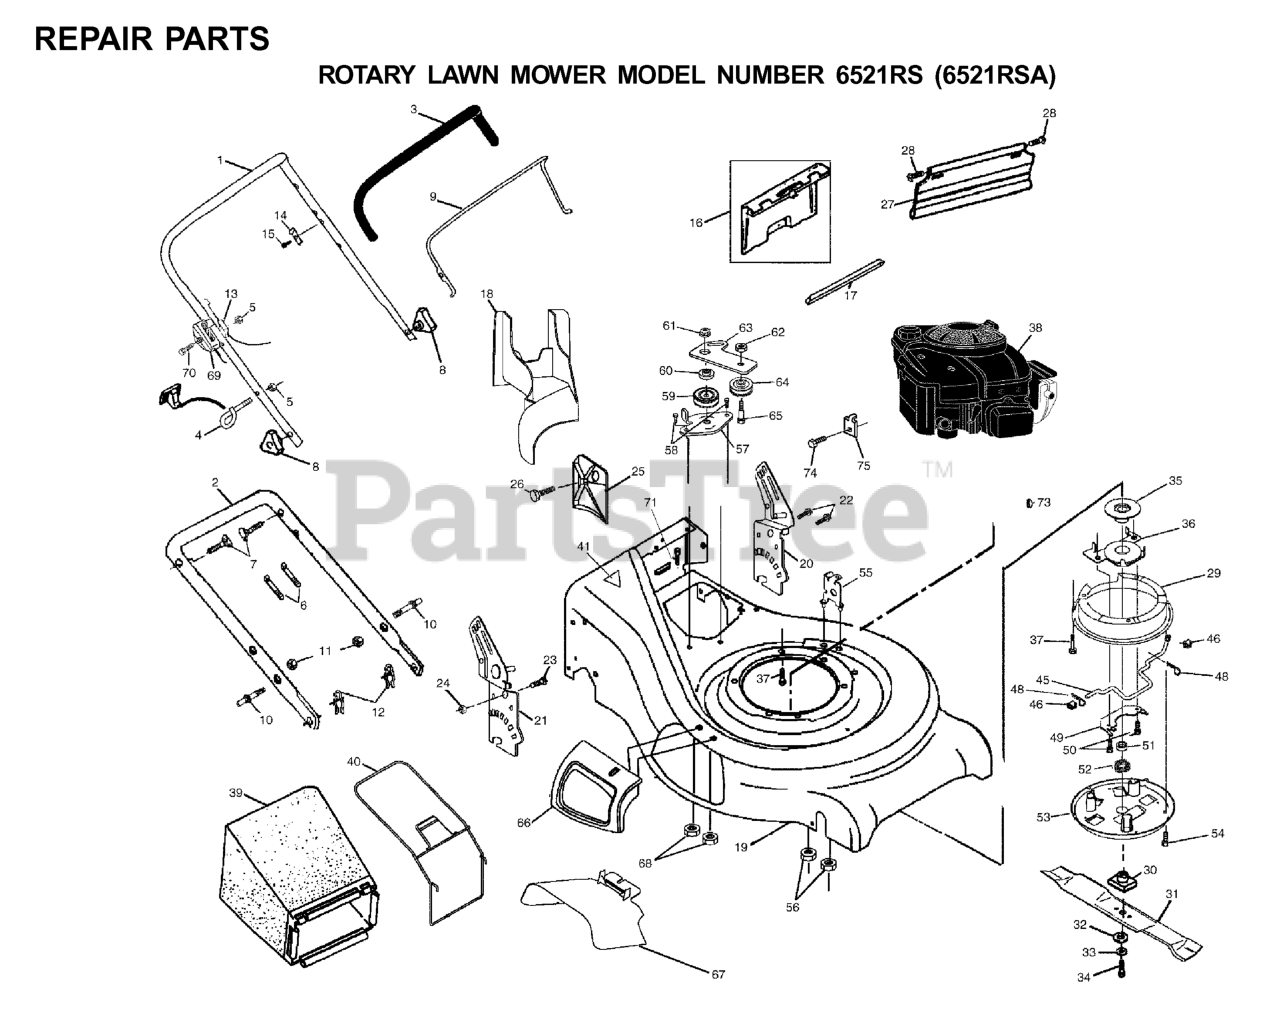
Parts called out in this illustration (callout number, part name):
1	HANDLE UPPER DLX COMF
2	HANDLE
3	GRIP.HANDLE.FOAM
4	ROPE GUIDE
5	NUT
6	TIE GUIDE
7	HANDLE BOLT
10	BOLT
11	NUT
12	HAIRPIN COTTER
13	ENGINE ZONE CONTROL
14	BRACKET UPSTOP
15	SCREW.HEX.HEAD.WASHER.10-16
16	KIT.DOOR.REAR.21.WRAPPED.BLACK
17	SEALING
18	MULCH PLUG
20	.RACKET
21	RIGHT HANDLE BRKT. ASSM.
22	SELF-TAPPING SCREW 5/16-18X3/4
23	BOLT, HEX HEAD 5/16-18
24	LOCKNUT
25	CLIPPING DEFLECTOR
27	REAR SKIRT
28	HINGE SCREW
29	BELT COVER, TOP
30	BLADE ADAPTOR
31	21" MULCH BLADE PREMIUM
32	WASHER,HARDEN
33	LOCKWASHER
34	SCREW, HEX HD 3/8-24 X 1-3/8
35	PULLEY, FIXED
36	BEARING SUPPORT ASM
37	BOLT 3/8-16X1-1/8
39	Grass Catcher Bag
40	FRAME.GRASS.CATCHER.WALK.21"
41	DECAL HYT
45	ROD.PULLEY.ENGAGE
46	BUSHING.PIVOT.ROD
48	RETAINER CLIP
49	CLAMP
51	SPACER RING
52	WASHER.WAVE.SPRING
53	BELT COVER, BOTTOM (1 2)
54	TAPPING SCREW
55	CABLE SUPPORT BRKT
56	NUT
57	BRACKET ASM
59	PULLEY.V-GROOVE.IDLER
60	IDLER ARM SPACER
61	NUT
62	LOCKNUT
63	IDLER ARM
64	IDLER PULLEY
65	SHOULDER BOLT
66	MULCH COVER
67	GUARD
69	THROTTLE CONTROL
70	SCREW 1/4-20 X 2.12
73	HI PRO KEY PM WSL
74	SCREW.HEX.HEAD.WASHER.10-16
75	CABLE CLAMP(ENGINE)
